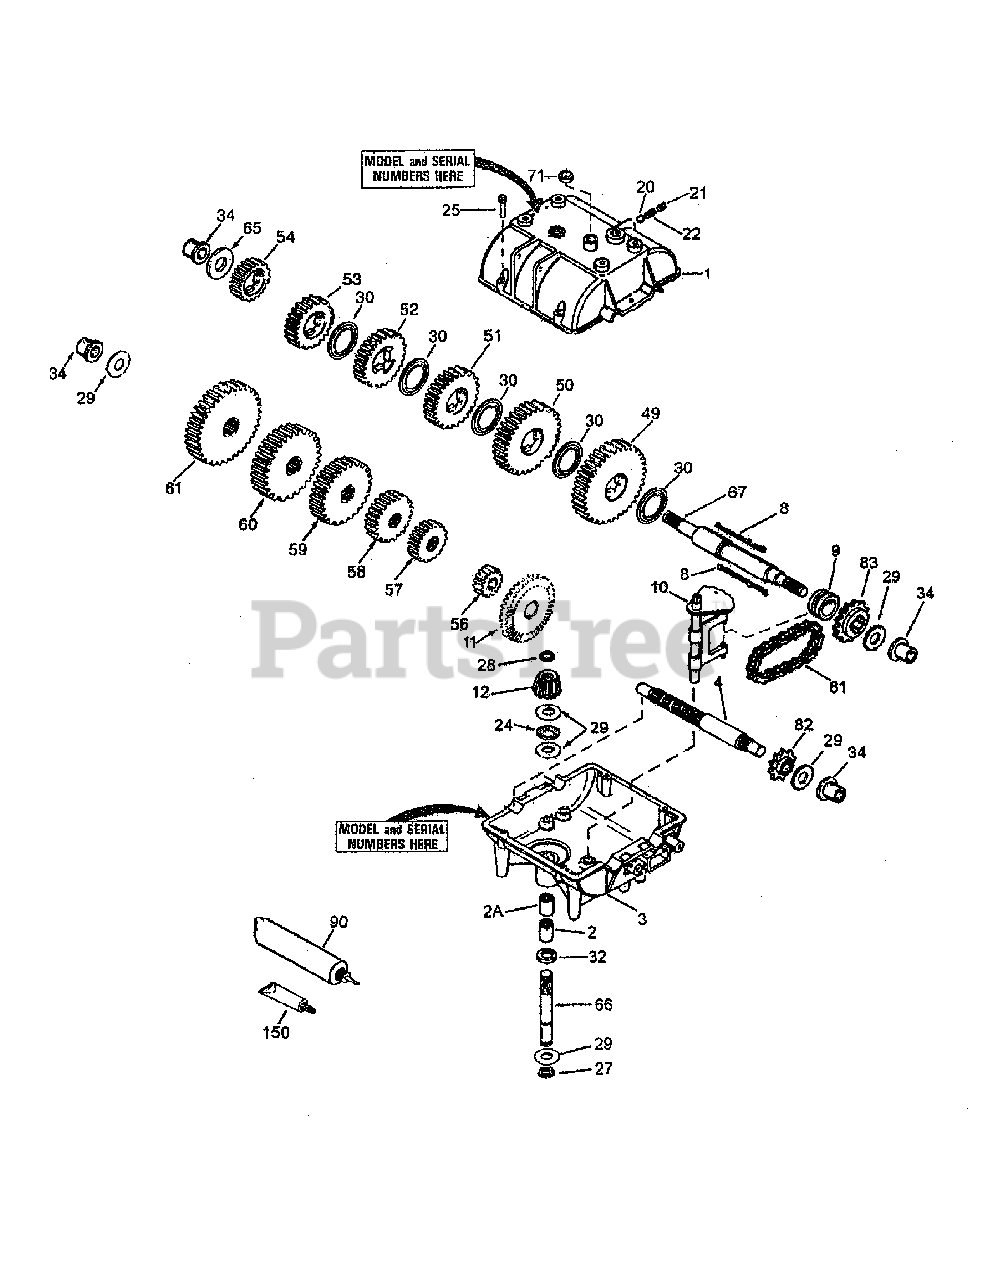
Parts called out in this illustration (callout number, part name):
1	Transmission Cover
2	Needle Bearing
2A	Needle Bearing
3	Transmission Case
4	Countershaft
8	Shift Key
9	Shift Collar
11	Bevel Gear (42 teeth)
12	Input Bevel Pinion (14 teeth-steel)
20	Steel Ball, 5/16" dia.
21	Set Screw, 3/8-16 x 3/8"
22	Spring
24	Thrust Bearing
25	Screw, 1.4-20 x 1-1/4"
27	Retaining Ring
28	Retaining Ring
29	Washer
30	Washer
32	O Ring
34	Flange Bushing
49	Spur Gear (35 teeth)
50	Spur Gear (32 teeth-steel)
51	Spur Gear (30 teeth)
52	Spur Gear (27 teeth)
53	Spur Gear (22 teeth)
56	Spur Gear (15 teeth)
57	Spur Gear (18 teeth-steel)
58	Spur Gear (20 teeth)
59	Spur Gear (23 teeth)
60	Spur Gear (28 teeth)
65	Thrust Washer
66	Input Shaft (3-11/16" long)
67	Shifter & Brake Shaft
71	Square Cut Ring
81	Roller Chain (No. 41 chain, 24 links)
82	Sprocket (9 teeth)
83	Sprocket (18 teeth)
90	Grease (32 oz. bottle Bentonite)
150	Gasket Eliminator (Loctite #515)
